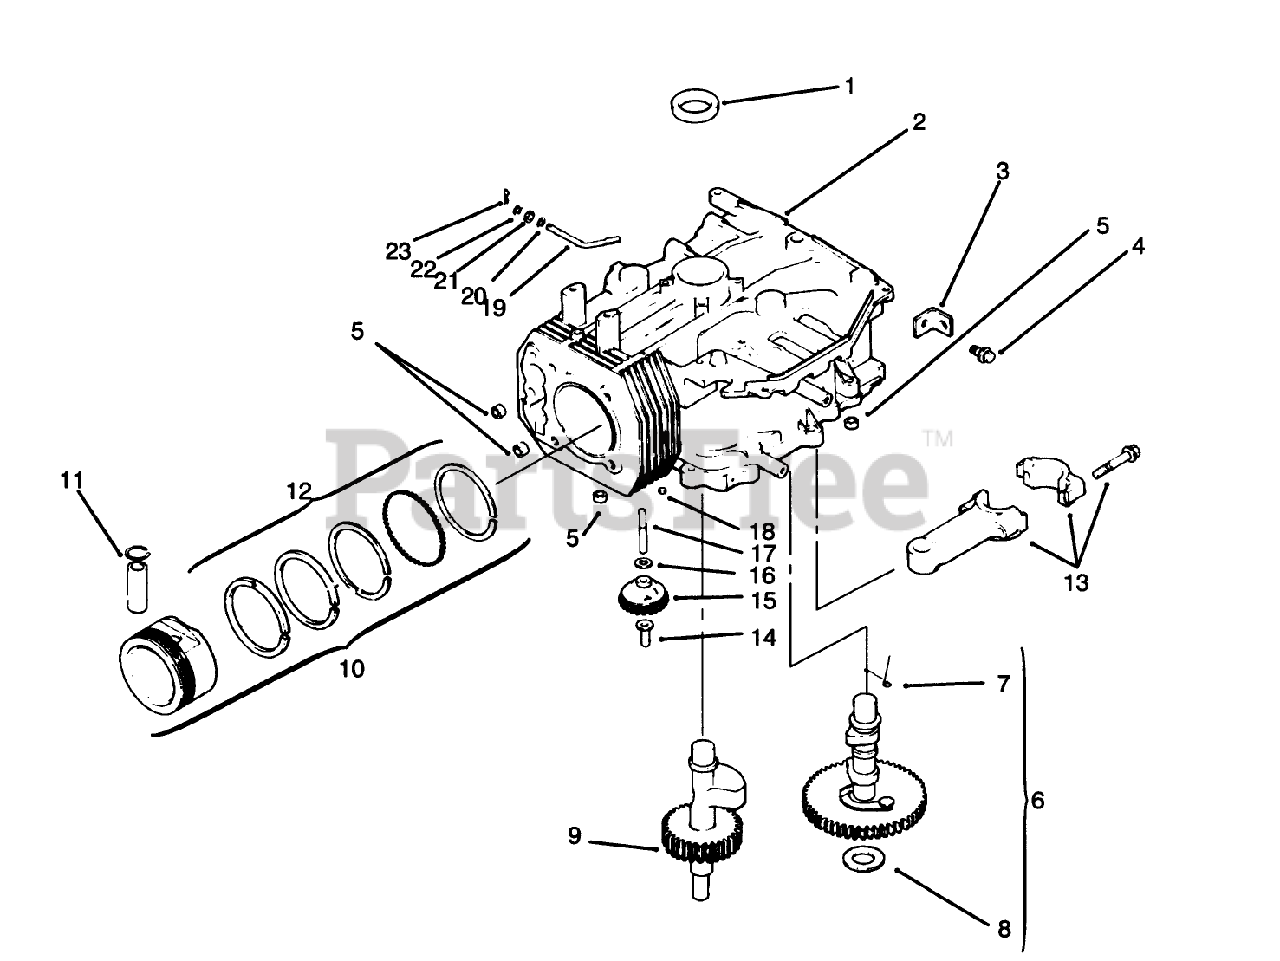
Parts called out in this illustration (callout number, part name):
1	Seal-Crankshaft (Only On: 72042, 72043, 72062, 72063)
3	Strap-Lifting (Only On: 72042,72043,72062,72063)
4	Screw M8x1.25x22 (Only On: 72042, 72043, 72062, 72063)
5	Pin-Dowel
6	Camshaft ASM Incl 7
7	Spring-Actuating (Only On: 72042,72043,72062,72063)
8	Shim-Camshaft
9	Shaft-Balance (Only On: 72042, 72043, 72062, 72063)
10	Piston ASM STD Incl 11-2
10	Piston ASM .25 Incl 11-2
10	Piston ASM .50 Incl 11-2
11	Retainer-Piston Pin (Only On: 72042, 72043,72062,72063)
12	Ring Set STD
12	Ring Set .25
12	Ring Set .50
13	Connecting Rod STD (Only On: 72042, 72063, 72062, 72043)
13	Connecting Rod .25 (Only On: 72042, 72063, 72062, 72043)
14	Pin-Governor
15	Gear-Governor ASM (Only On: 72042, 72063, 72062, 72043)
17	Shaft-Govenor Gear
19	Shaft-Governor Cross (Only On: 72042, 72063, 72062, 72043)
20	Washer-Governor Shaft (Only On: 72042, 72063, 72062, 72043)
21	Seal
22	Washer
23	Pin-Hitch
